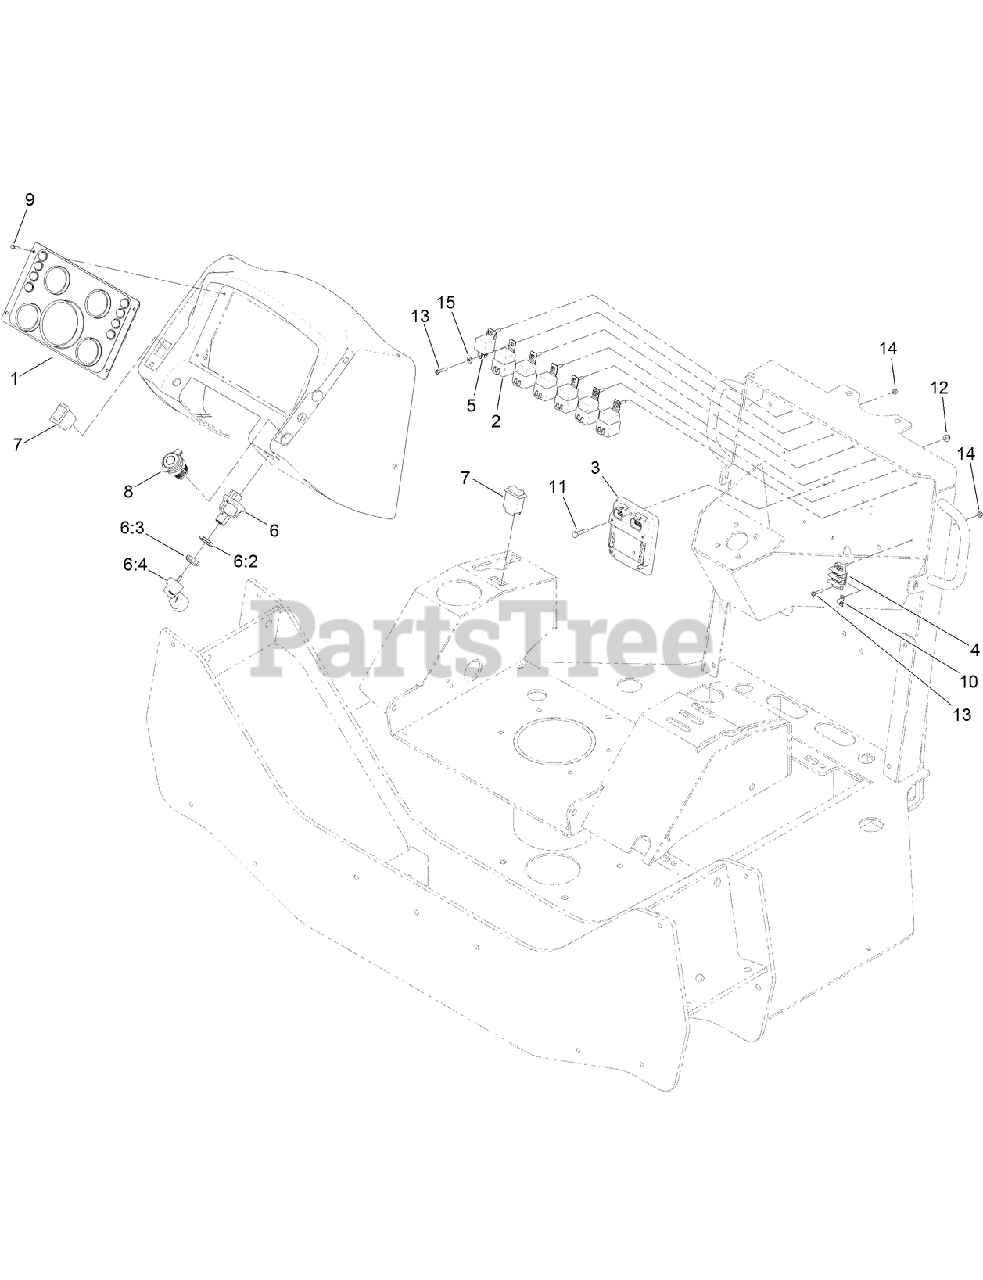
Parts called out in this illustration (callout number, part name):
1	INSTRUMENT PANEL ASM
2	RELAY-MINI
3	MODULE-CONTROL, STANDARD
4	BLOCK-TERMINAL, GROUND
5	RELAY
6	IGNITION SWITCH ASM
6:2	NUT-HEX
6:3	NUT-FACE
6:4	SET-KEY, IGNITION
7	SWITCH-ROCKER, 2 POLE (ON/OFF)
8	RECEPTACLE-12V
9	SCREW-HH
10	STRIP-JUMPER
11	SCREW-HH
12	NUT-HF
14	NUT-LOCK, NI
15	WASHER-FLAT
